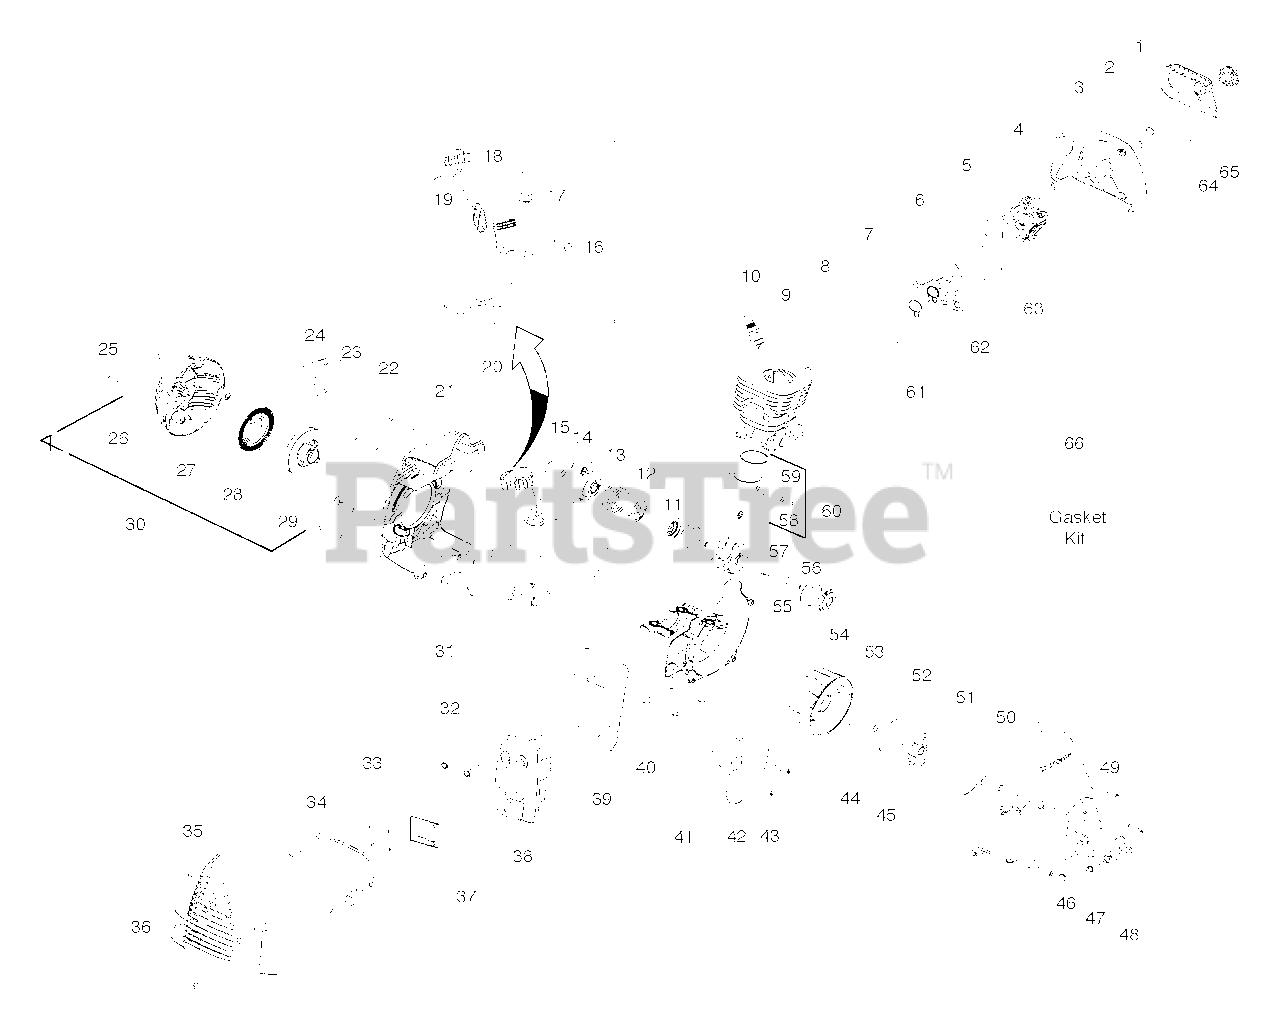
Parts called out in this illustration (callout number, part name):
2	Nut-Carb. Screw
3	Air Box
4	Lever - Choke
5	Kit-Carb. Gasket
6	Adaptor-Carb.
7	Kit-Gasket (foam)
9	Cylinder
10	Plug-Spark (RCJ-8Y)
11	Kit-Crankshaft seal
12	Washer-Starter
13	Spring-Starter Cup
14	Assy-Starter Cup
15	Coupling-Starter
16	Assy-Fuel Filter
17	Kit-Fuel Line
18	Assy-Cap w/ret.
19	O-ring - Fuel Cap
20	Assy-Fuel Tank
21	Shroud-Rear
24	Handle-Starter
26	Starter Hsg. w/eyelet
27	Kit-Starter Spring
28	Kit-Starter Pulley
30	Assy-Starter Hsg.
31	Isolator-Tank
32	Bolt-Muffler
34	Shield-Heat
36	Guard-Muffler
37	Kit-Spark Arrestor
38	Assy-Muffler
39	Gasket-Paper Metal
42	Assy-Leadwire
45	Washer-Clutch
50	Assy-Fan Housing
51	Assy-Clutch Drum
52	Kit-Clutch Assy.
57	Kit-Crankshaft
58	Retainer-Piston Pin
59	Ring-Piston
60	Kit-Piston
61	Kit-Gasket (adaptor seal)
63	Kit-Carb.
64	Cover-Air Box
66	Kit-Gasket
